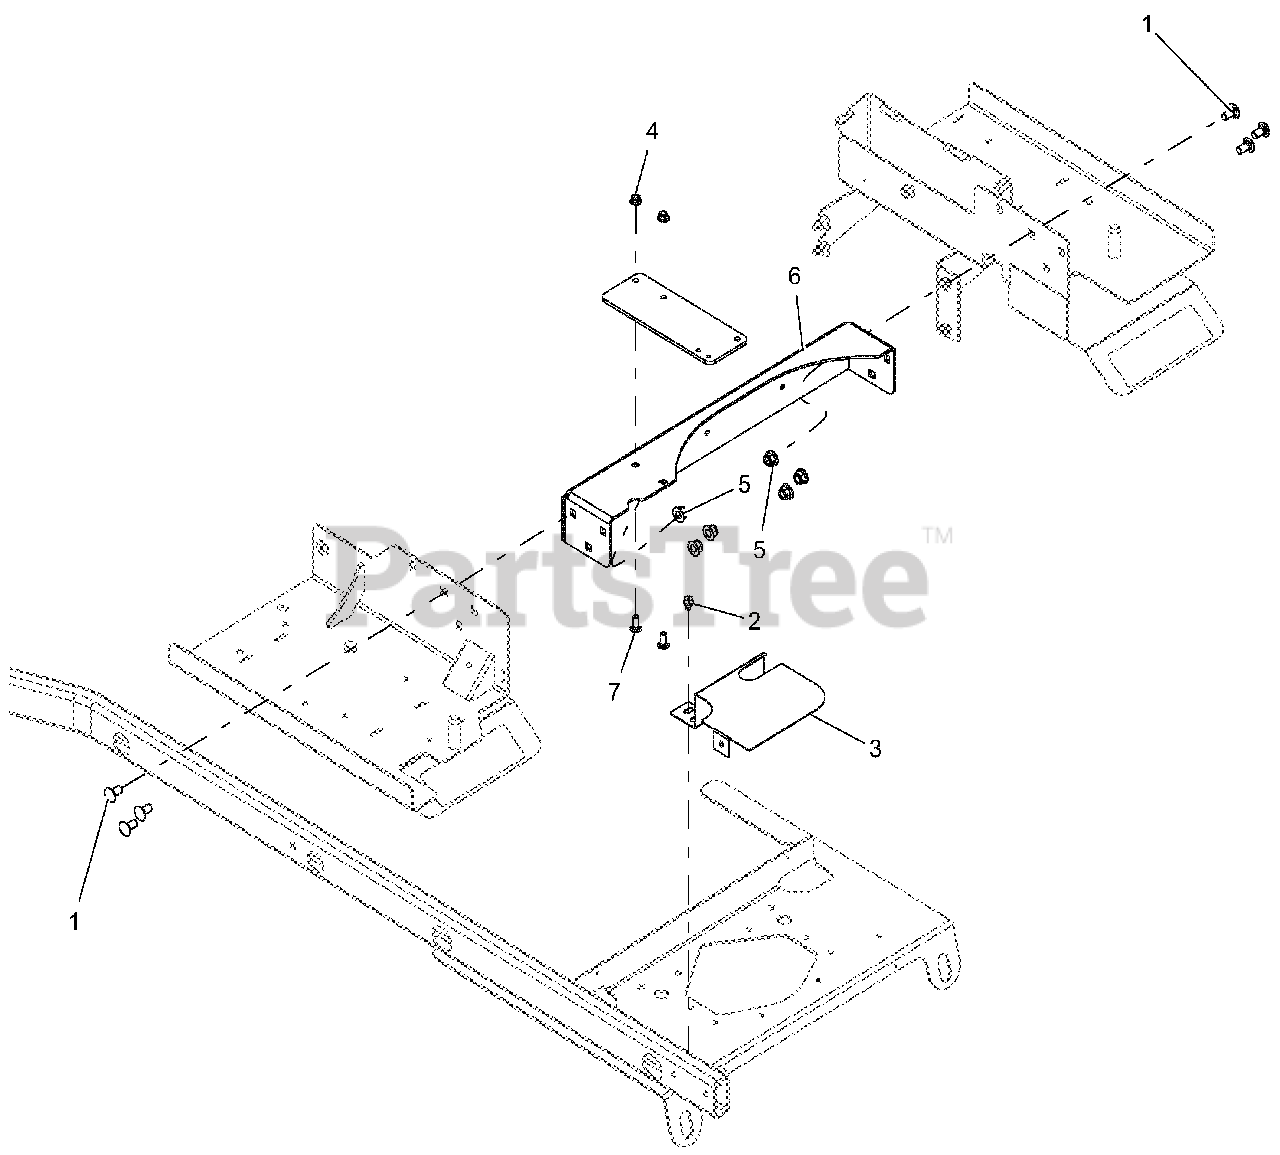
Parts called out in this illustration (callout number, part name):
1	BLT-RDHDSQNK .50-13X1.00 G5 Y
2	SCR-TAP .38-16X.50 HWH TR YWZ
3	GUARD, LP-MUFFLER-BLACK
4	NUT-LK-NYL-FLG .38-16 YWZC
5	NUT-LK-NYL-FLG .50-13 YWZC
6	TANK MNT CROSS SUPPORT W/SAFETY DECAL
7	BLT-RDHDSQNK .38-16X1.00 G5 YWZC
